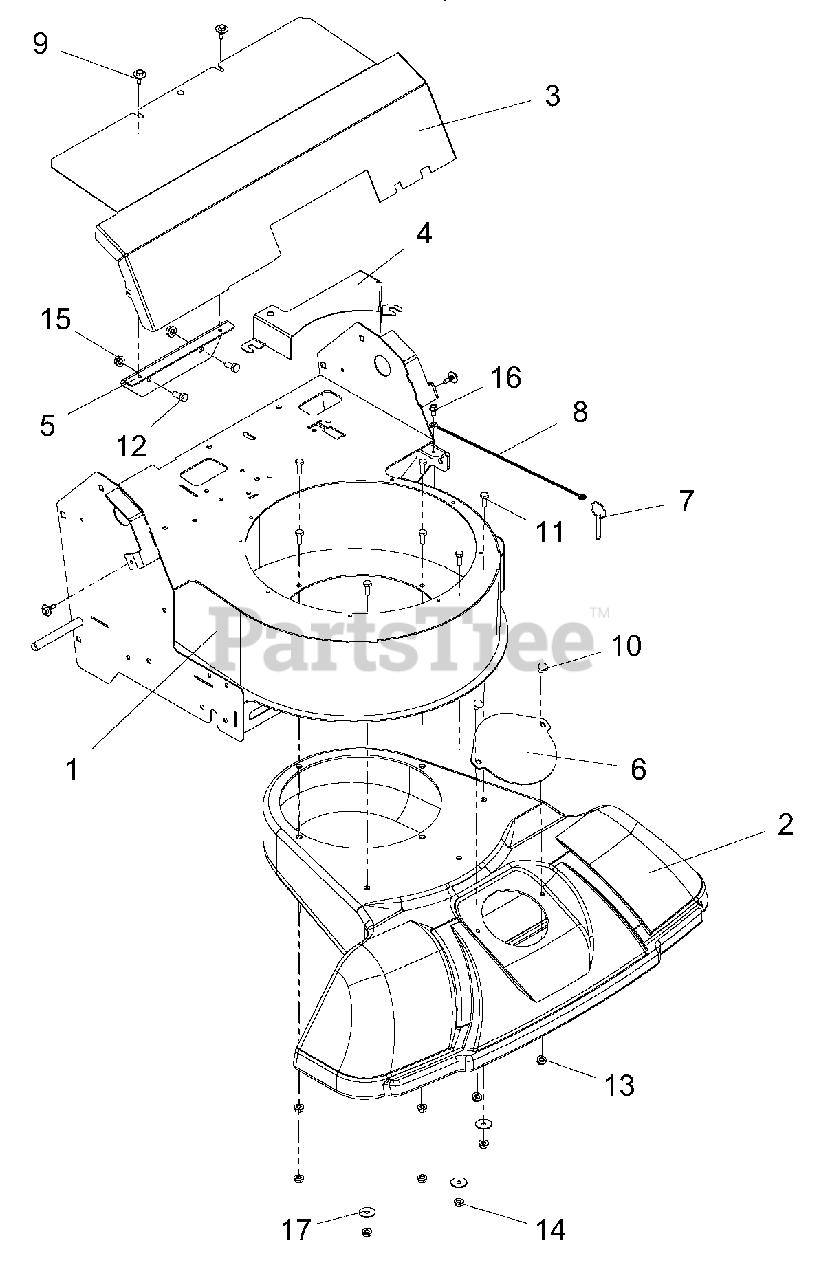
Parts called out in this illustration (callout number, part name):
1	KIT, APV FRAME ARIENS W/DECAL
2	INLET-MOLDED, APV FRONT
3	GUARD, TRANSMISSION - APV
4	GUARD, BELT - APV
5	BRKT, SUPPORT - TRANS GUARD
6	COVER, HOSE INLET
7	PIN, RING DETENT .25X1.50 ZC
8	CBL,HOOD
9	SCR-TAP .25-20X.5 CAPTIVE
10	BLT-RDHDSQSHNK.25-20X.50 YWZC
11	@BLT-HEX .25-20X.75 GR5 YWZC
12	@BLT-HEX .31-18X.75 GR5 YWZC
13	@NUT-LK-CTR-FLG .25-20 YWZC
14	@NUT-LK-TOP-FLG .25-20 YWZC
15	@NUT-LK-TOP-FLG .31-18 YWZC
16	SCR-TAP .25-20X.50 HWH TR YWZ
17	WSHR-FL-STL .281X1.000X.063
